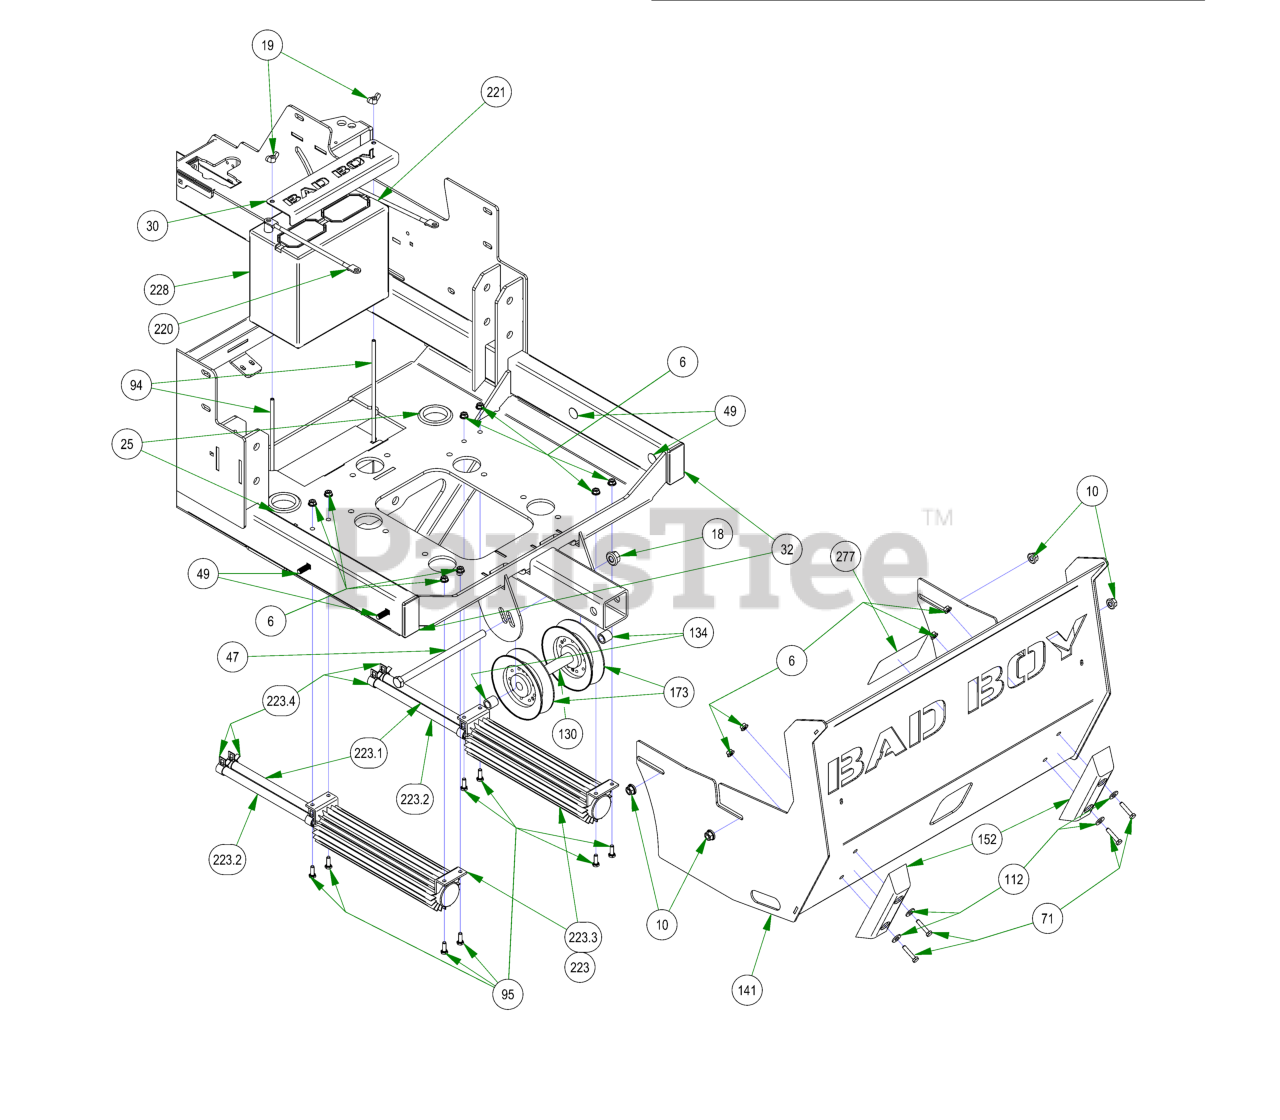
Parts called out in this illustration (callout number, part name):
6	1/4-20 NYL INSERT FLANGE LOCKNUT ZINC
10	3/8-16 NYLON INSERT FLANGE LOCKNUT (GR.F) ZINC
18	1/2-13 NYLON INSERT FLANGE LOCKNUT ZINC
19	1/4-20 WING NUT FORGED (TYPE A) LIGHT SERIES ZINC
25	2019 2" x .25 Rubber Grommet
30	2019 Horizontal Battery Hold Down Cover
32	1 1/2 x 3 Frame Plug
47	1/2-13 X 8-1/2 HEX CAP SCREW (GR.5) ZINC
49	3/8" x 2 1/2" Carriage Bolt
71	1/4-20 X 1-1/4 HEX CAP SCREW (GR.5) ZINC
94	1/4-20 X 9 CARRIAGE BOLT ZINC
95	1/4-20 X 3/4 HEX CAP SCREW (GR.5) ZINC
112	1/4 USS FLAT WASHER (3/4 OD) ZINC
130	2019 Pulley Spacer .75 x .5 x 4.375
134	.51 ID X .75 OD X .75 LGTH SOLID SPACER ZINC
141	2019 Horizontal Suspension Rear Cover
152	8" Rubber Bumper
173	2019 Outlaw Horizontal Rear V Pulley
220	Red Battery Cable - Diesel
221	Black Battery Cable - Diesel
223	Renegade Oil Cooler Assembly
223.1	3/8" Clear Hose
223.2	3/8" Clear Hose
223.3	2019 12" Oil Cooler With Fittings
223.4	3/8" Hose Clamp
228	Battery - Diesel/Renegade Models PF-516
235	2022 Horizontal Diesel Frame
277	2019 Renegade Pump Belt Route Decal
